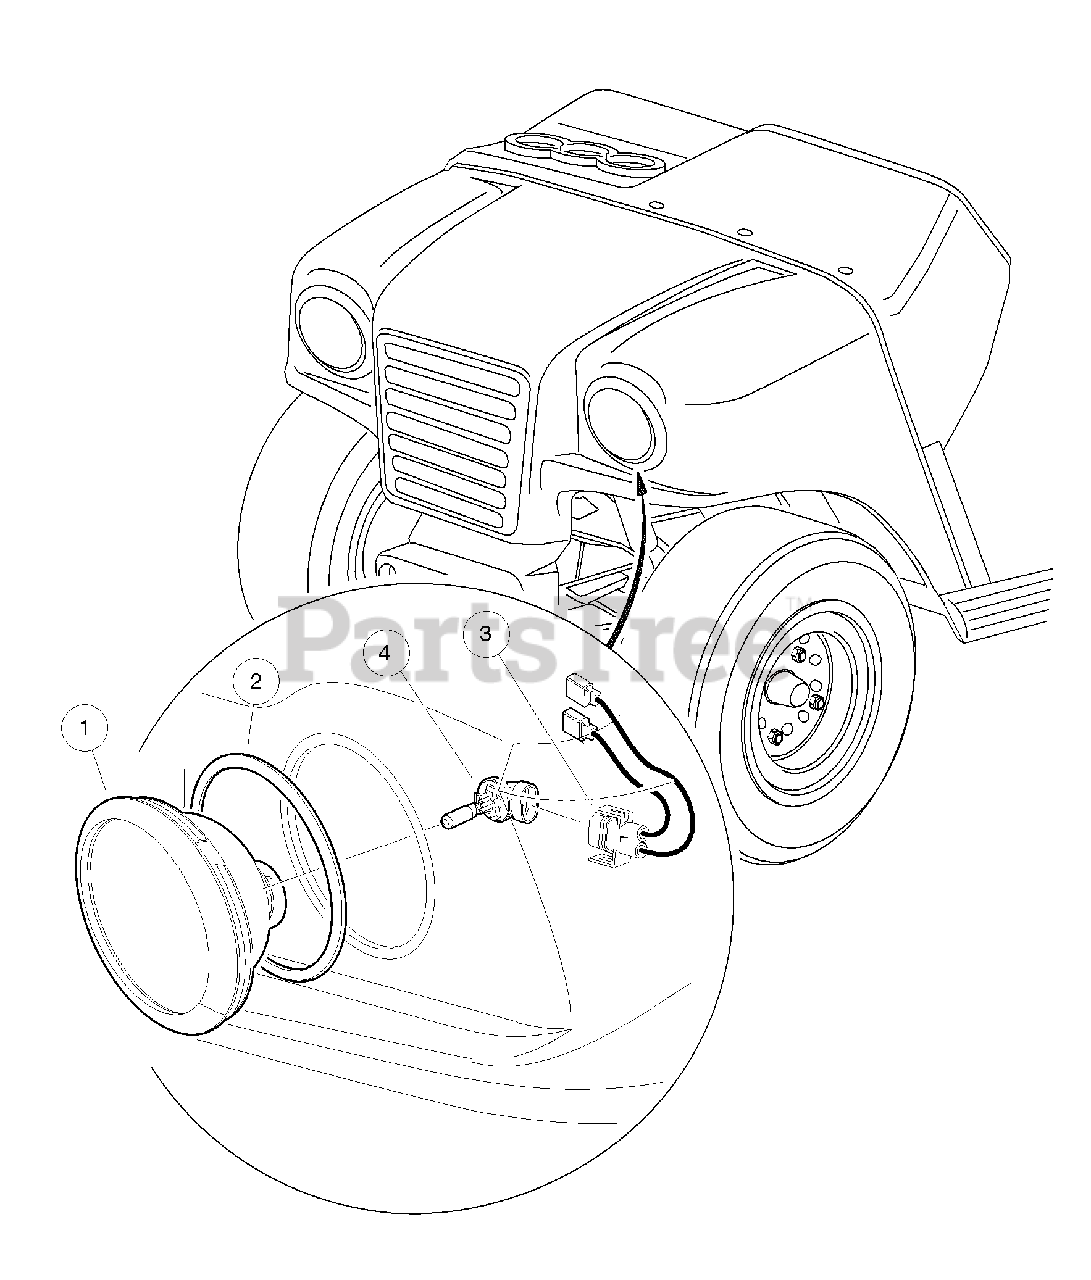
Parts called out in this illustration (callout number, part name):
1	Assembly, Headlight
2	Spacer, Headlight, Oval
3	Harness, Headlight
4	Bulb, Headlight, Oval
